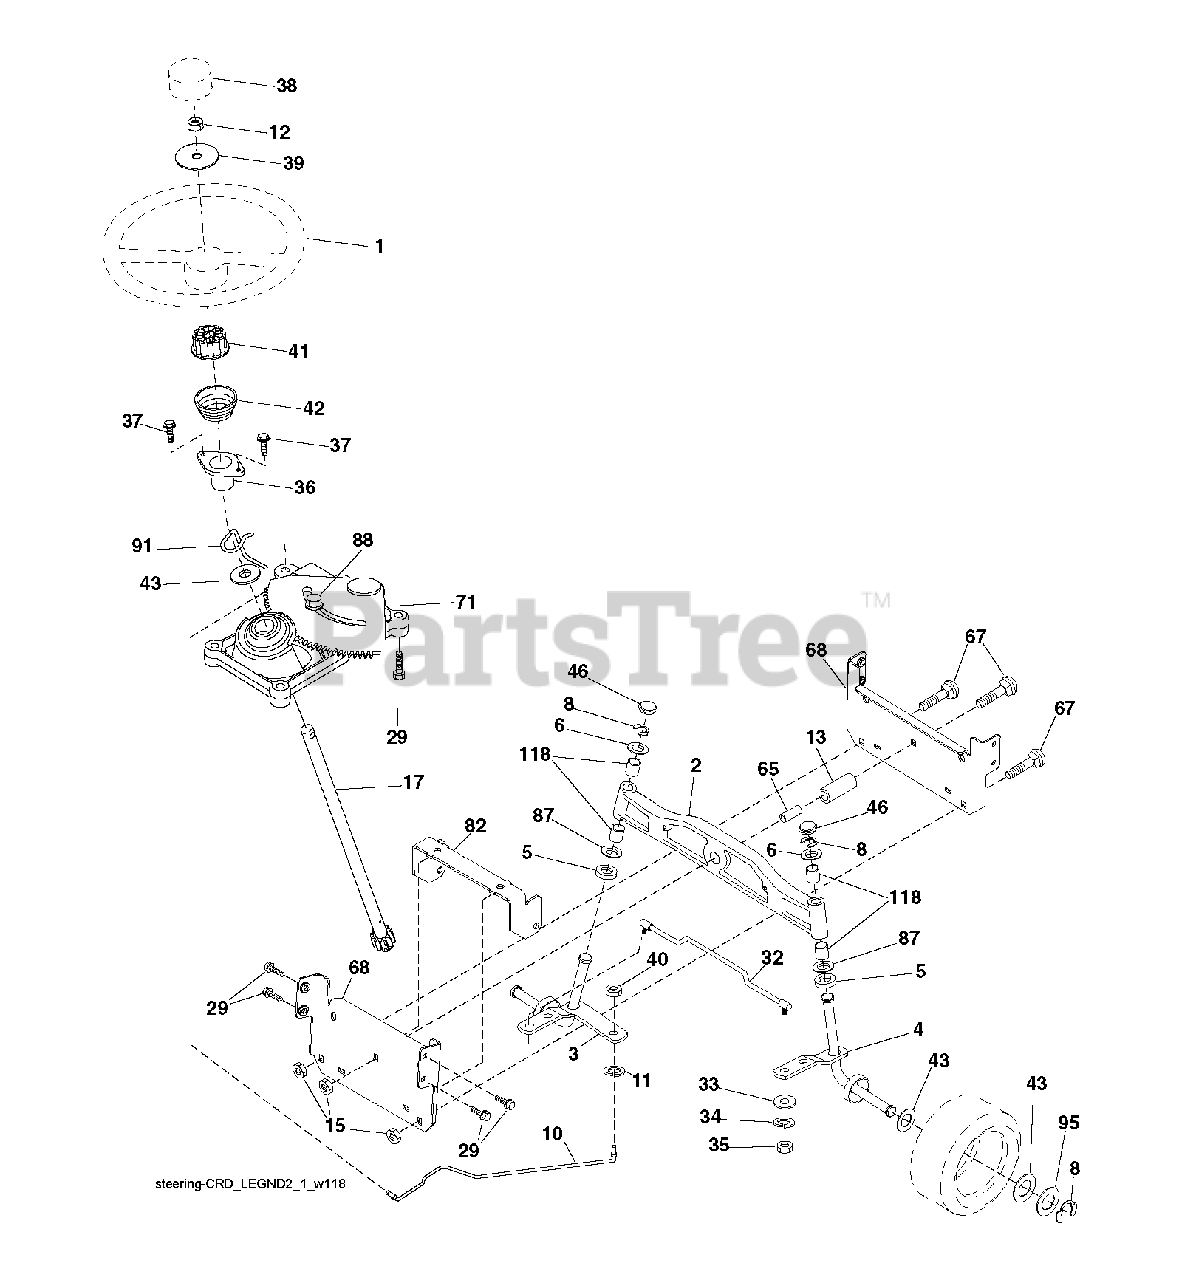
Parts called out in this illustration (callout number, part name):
1	WHEEL.STEERING.STDSRR.BLK/OV
2	AXLE.ASM.LT.CAST.LGHTWGHT
3	SPINDLE.ASM.LH.15"TIRES
4	SPINDLE.ASM.RH.15"TIRES
8	RING CLIP
10	DRAGLINK.15".TIRES.2001
11	WASHER, LOCK 3/8
12	NUT.HEX.1/2-20
13	TUBE, PIVOT AXLE
15	NUT
17	SHAFT ASM STRG
29	SCREW, 3/8-16X3/4
33	WASHER M
34	LOCKWASHER
35	NUT, CROWNLOCK
36	BUSHING, STRG. BLK
38	CAP.WHL.STRNG.STDSRRD.SRS.BLK
39	WASHER 9/16"ID, 2 3/8"OD
40	NUT CROWNLOCK 3/8-24
41	ADAPTER, WHEEL STNG..
46	CAP.SPINDLE
65	SPACER.BRACE.AXLE
67	BOLT CARRIAGE
68	BRACE.AXLE.15"TIRES
71	STEERING ASM
82	BRACKET.SUSP.CHASSIS.FRONT.15
87	WASHER, FLAT .781 X 1 1/2"
88	BOLT, SHOULDER 7/16-20
91	CLIP.STEERING
95	WASHER.HARDENED
118	BUSHING, AXLE CAST
